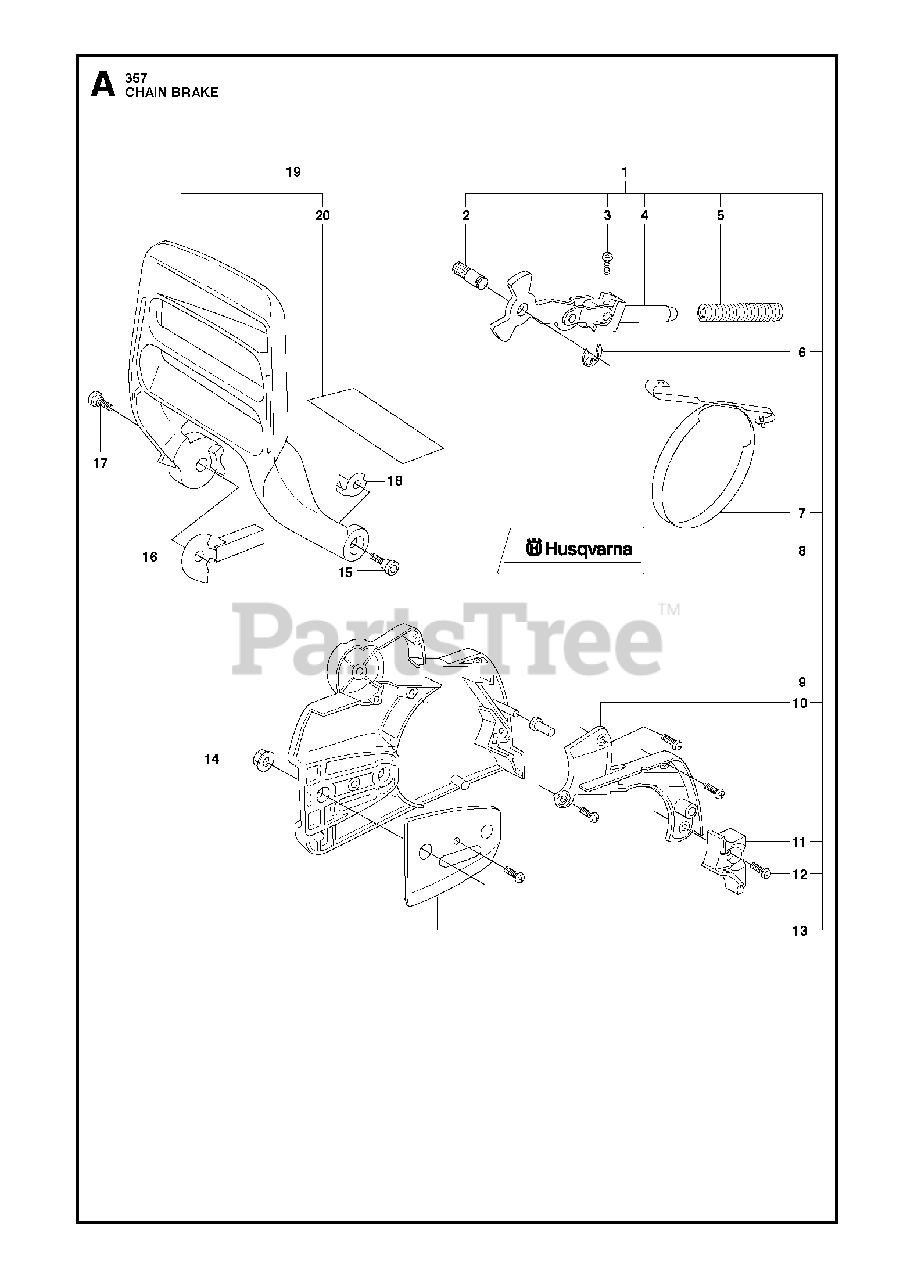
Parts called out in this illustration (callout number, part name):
1	CHAIN BRAKE
2	PIN
3	SCREW
4	JOINT
5	SPRING
6	E-RING 4
7	BRAKE BAND
8	DECAL
9	SLEEVE
10	COVER
11	PROTECTOR
12	SCREW
13	PLATE
14	NUT M8 FLANGE
20	PROTECTOR
